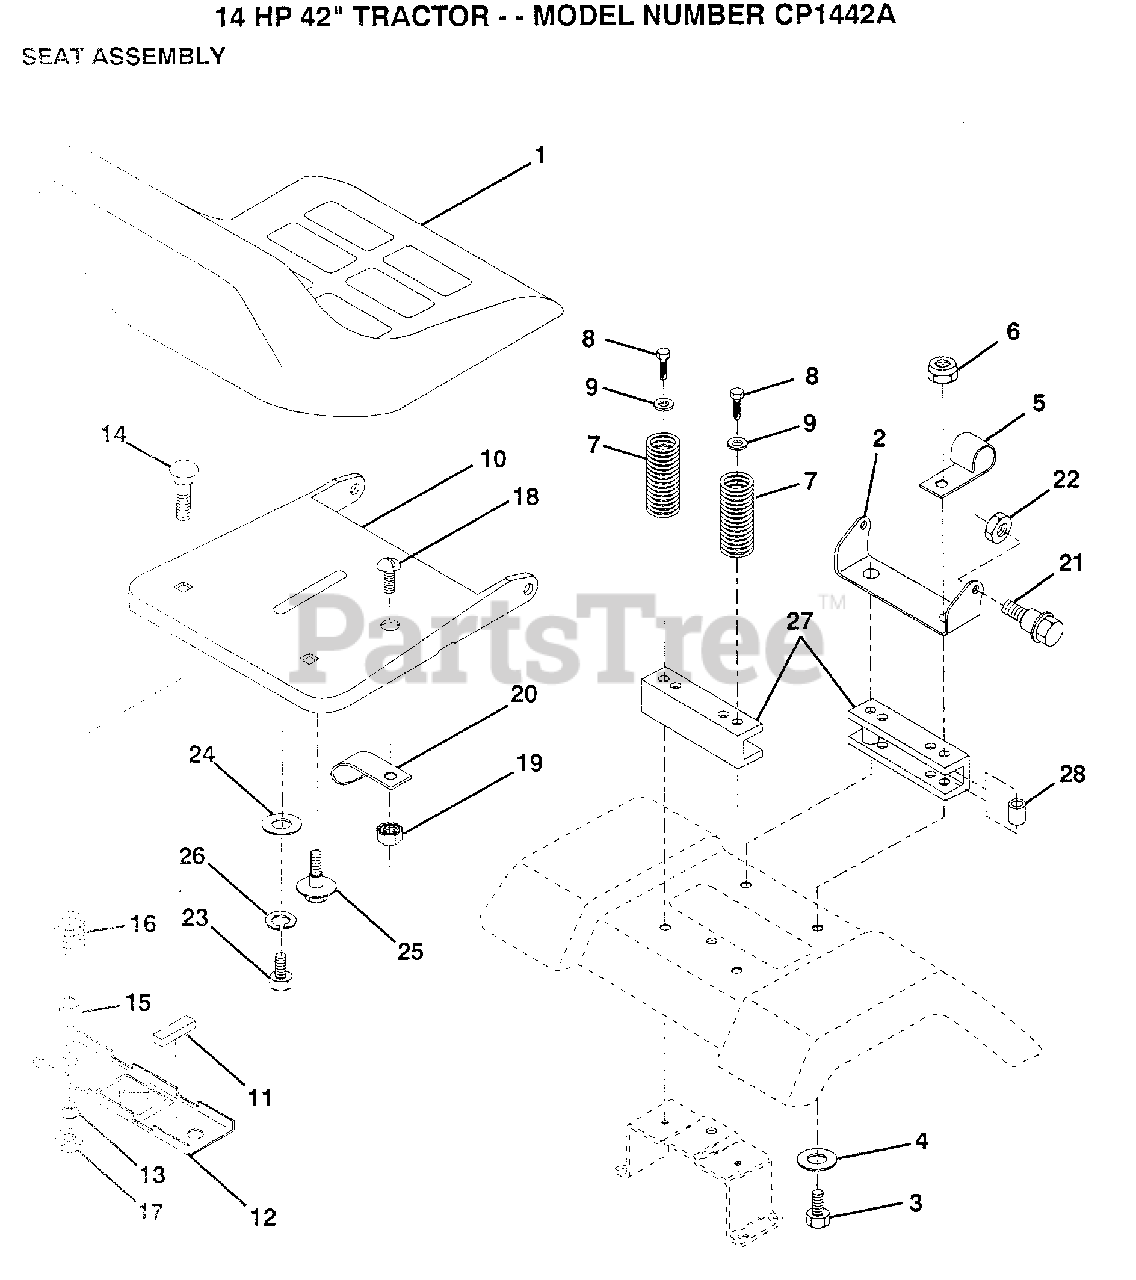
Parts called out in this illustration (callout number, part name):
3	BOLT
4	WASHER PM
5	CLIP T
7	SPRING COMPRESSIO
8	SCREW
9	WASHER
11	STRIP FORM
12	BRKT SWITCH
13	BUSHING
15	SPROCKET ASM.
16	SPRING
19	"NUT,KEPS"
21	BOLT.SHLD.5/16-18
23	BOLT
24	WASHER
25	"BOLT,SHOULDER"
26	LOCKWASHER
27	SEAT SPACER
28	SPLIT SPACER
